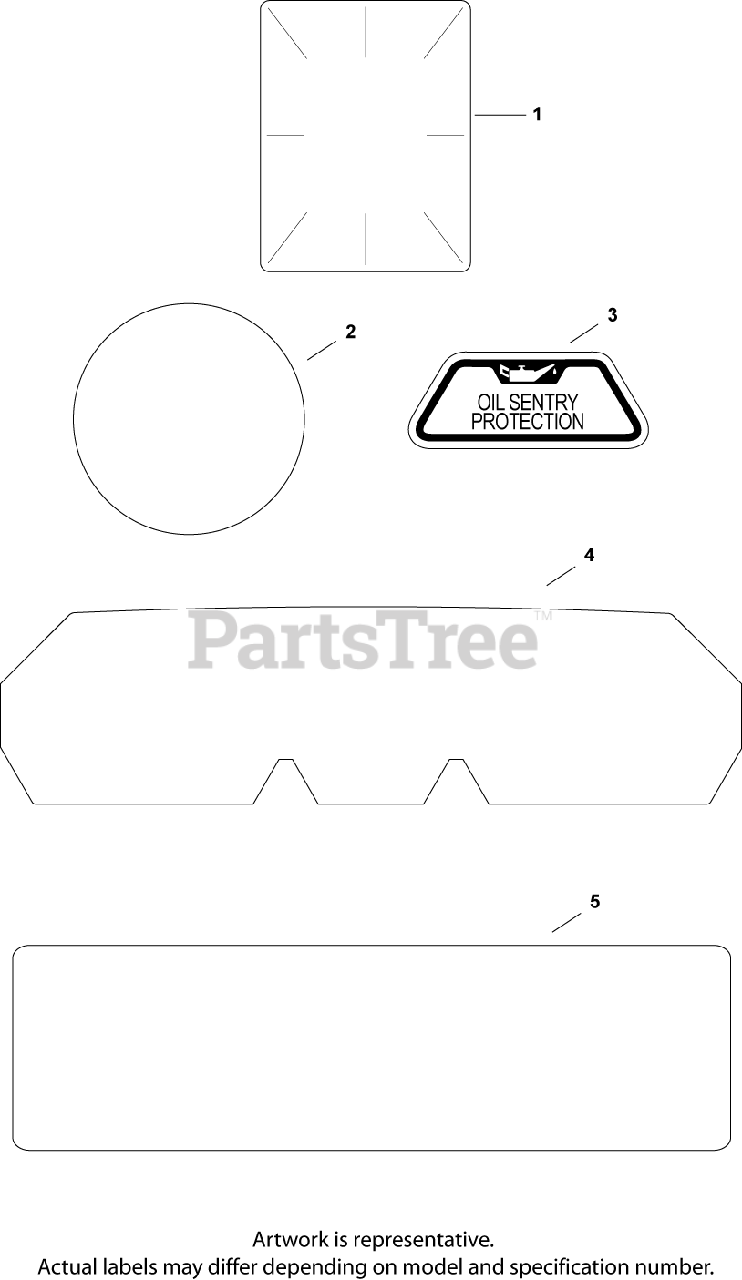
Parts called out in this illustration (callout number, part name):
1	DECAL, CLEAR LAMINATE USE 25 113 70-S
2	DECAL, GRASS SCREEN USE 24 113 499-S
3	DECAL, OIL SENTRY - (#DSC)
4	DECAL, 22 HP USE 24 113 138-S
5	DECAL, 22 HP
